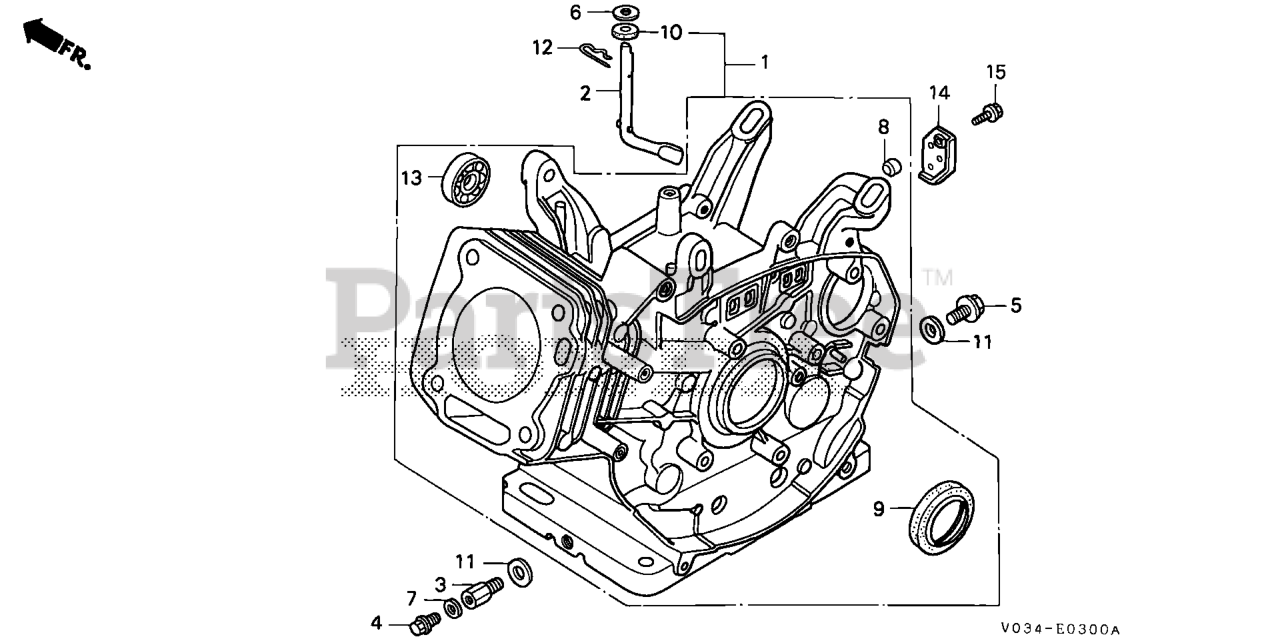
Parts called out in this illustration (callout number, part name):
1	CYLINDER ASSY. (SELF STARTER)
2	SHAFT, GOVERNOR ARM
3	EXTENSION, OIL DRAIN
4	BOLT, DRAIN PLUG
5	BOLT, DRAIN PLUG
6	WASHER (8.2X17X0.8)
7	WASHER, DRAIN PLUG (10.2MM)
8	PLUG, SEALING
9	OIL SEAL (35X52X8)
10	OIL SEAL (8X14X5)
11	WASHER, DRAIN PLUG (12MM)
12	PIN, LOCK (10MM)
13	BEARING, RADIAL BALL (6202)
